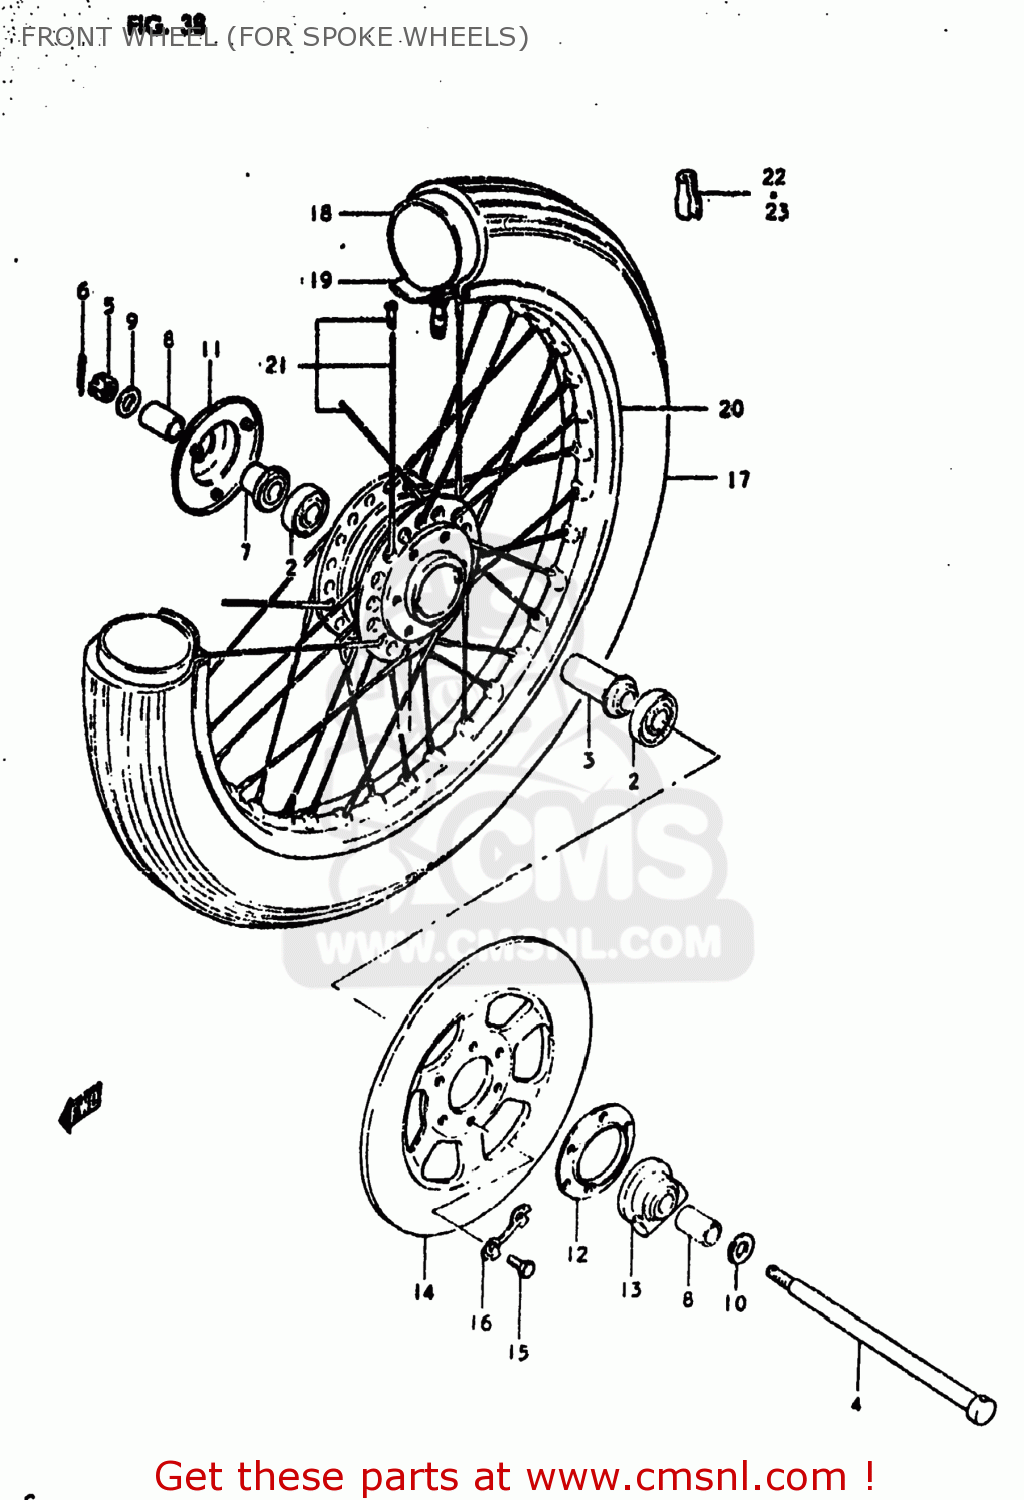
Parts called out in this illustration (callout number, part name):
1	DRUM,FRONT HUB
2	BEARING
3	SPACER,FR HUB BEARING
4	AXLE,FRONT
5	NUT 12MM
6	COTTER PIN
7	SPACER,FR AXLE,R
8	SPACER(15X22X30)
9	WASHER
10	WASHER
11	COVER,FR HUB,R
12	DUST SEAL,SPEEDOMETER GEAR BOX
13	BOX ASSEMBLY,SPEEDOMETER GEAR
14	DISC,BRAKE
15	BOLT(8X25)
16	WASHER
17	TIRE,FRONT
18	TUBE,INNER
19	PROTECTOR,WHL INR TUBE
20	RIM,FR WHEEL
21	SPOKE SET,FRONT
22	BALANCER,WHEEL (B)
23	BALANCER,WHEEL (30G)
